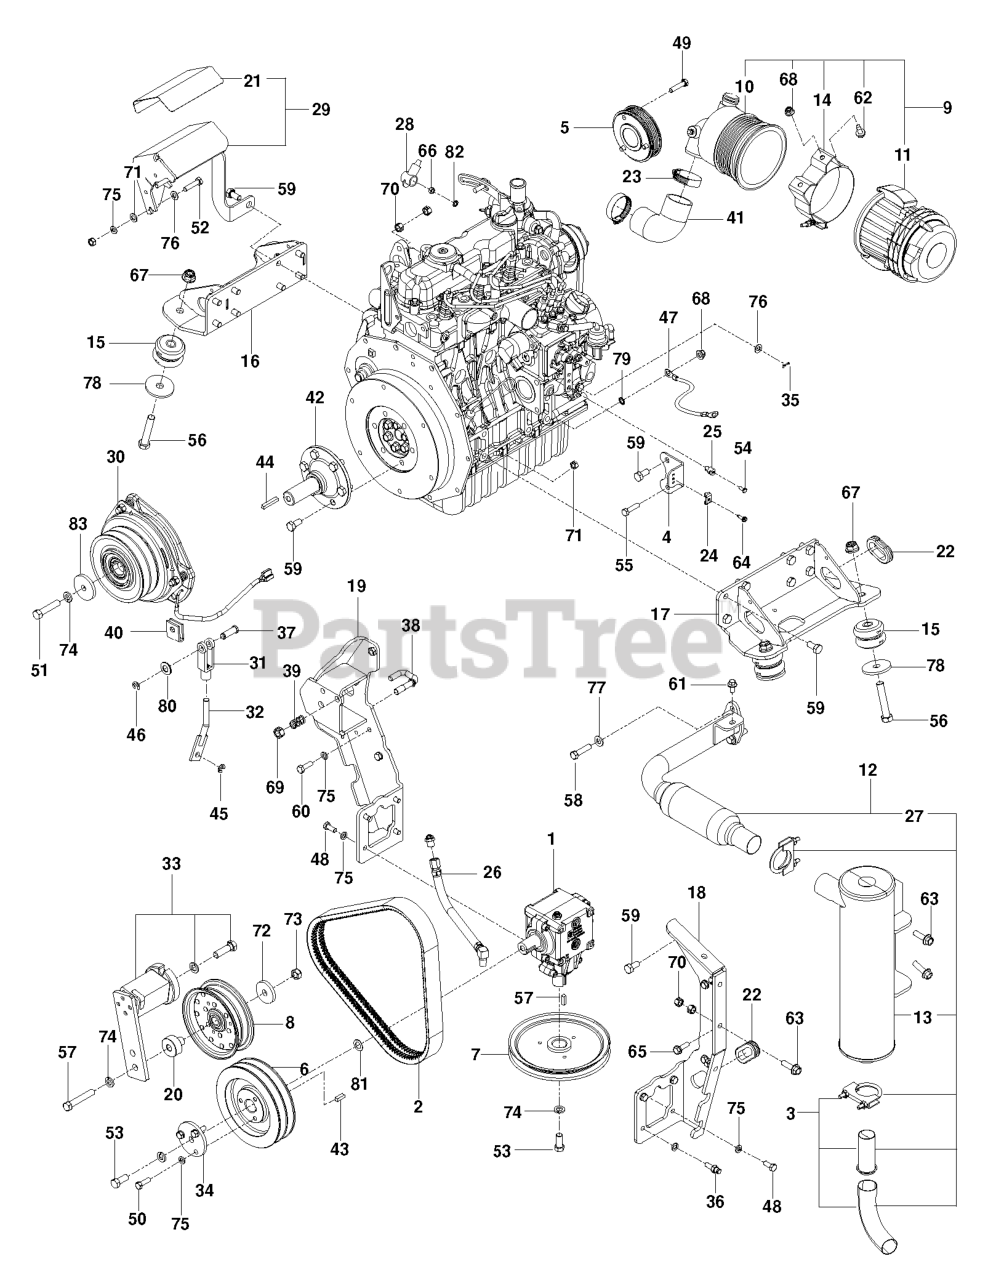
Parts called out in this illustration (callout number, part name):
1	GEAR BOX, 90 DEGREE
2	BELT, CLUTCH
3	KIT.SPARK.ARRESTER
4	BRACKET, THROTTLE
5	PULLEY, CRANK
6	PULLEY, GEAR BOX
7	PULLEY, DRIVE, DECK
8	IDLER PULLEY
9	AIR FILTER ASSY - NON-TURBO
10	BODY - 90 DEG
11	PRECLEANER ASM
12	MUFFLER.DIESEL.KUBOTA
13	MUFFLER, DIESEL
14	MOUNTING BRACKET
15	ISOLATOR, ENGINE
16	MOUNT, MOTOR, LT - BLK
17	MOUNT, MOTOR, RT - BLK
18	MOUNT, GEAR BOX, BLK
19	MOUNT, GEAR BOX, BLK
20	MOUNT, IDLER
21	SHIELD, HEAT BARRIER
24	CLAMP, CABLE
25	SWIVEL, THROTTLE
26	HOSE, VENT
27	PIPE, MANIFOLD, DIESEL
28	TERMINAL COVER-SM
29	SHIELD, HEAT
30	CLUTCH, OGURA, DIESEL
31	YOKE, CLEVIS
32	LINKAGE, ANTI-ROTATION
33	TENSIONER, LOVEJOY, SE27
34	PLATE, PULLEY
35	COTTER PIN 3/32 X 1/2
36	PIN, PIVOT
37	PIN, 7/16 CLEVIS
38	PIN, DETENT
39	SPRING, COMPRESSION
40	SPACER, RUBBER
41	HOSE, AIR INTAKE
42	SHAFT, PILOT
43	KEY 1/4 SQ X 3/4
44	KEY 1/4 SQ X 1-1/2
45	E RING 3/8"
46	RING, E, 7/16
47	GROUND CABLE
48	SCREW 5/16C X 1 HEX CAP
49	HCS MB 1.25 X 35 GR 8.8 ZD
50	HCS 5/16C X 1
51	HCS 7/16-20 X 2 G8 ZN
52	HTB M8-1.125 X 25MM
53	SCREW 7/16-20 X 1 HHB GR5
54	HCS #10-24 X 1/2
55	HCS 5/16C X 1 1/4
56	HCS 1/2C X 2 3/4
57	HCS 7/16-20 X 2-3/4
58	HCS 3/8C X 1 1/2
59	HCS M10-1.25 X 20 GR 8.8 ZD
60	M8X1.25X25 HHB GR8.8
61	SCREW M8X1.25X16 HHB GR 8.8
62	BOLT 5/16-18 X 3/4
63	HHFS 3/8-16 X 1.25 GD 5
64	SCREW #10 X 1/2 SELF TAPPING
65	5/16-18X1 TAP SCREW
66	NUT M6 X 1.0 HEX
67	NUT, 1/2-13 HEX FLG NYLOC ZD
68	5/16-18 NYLOC FLANGE NUT
69	NUT 7/16C CENTERLOCK
70	NUT 3/8C CENTERBLOCK
71	NUT 5/16C CENTERLOCK
72	NUT, 7/16-20 HEX NYLOC ZC
73	SPINDLE WASHER
74	WASHER 7/16 LOCK
75	WASHER.LOCK.HVY.HLCL.SPR.5/16
76	FLAT WASHER 5/16 SAE
77	WASHER 3/8 SAE FLAT
78	WASHER, HEAVY
79	WASHER 5/16 EXT STAR
80	WASH 1/2 X 1 SPRG STL & NEOP
81	WASHER .515 X .874 X .031
82	WASHER 1/4 INT TOOTH
83	BLADE WASHER
